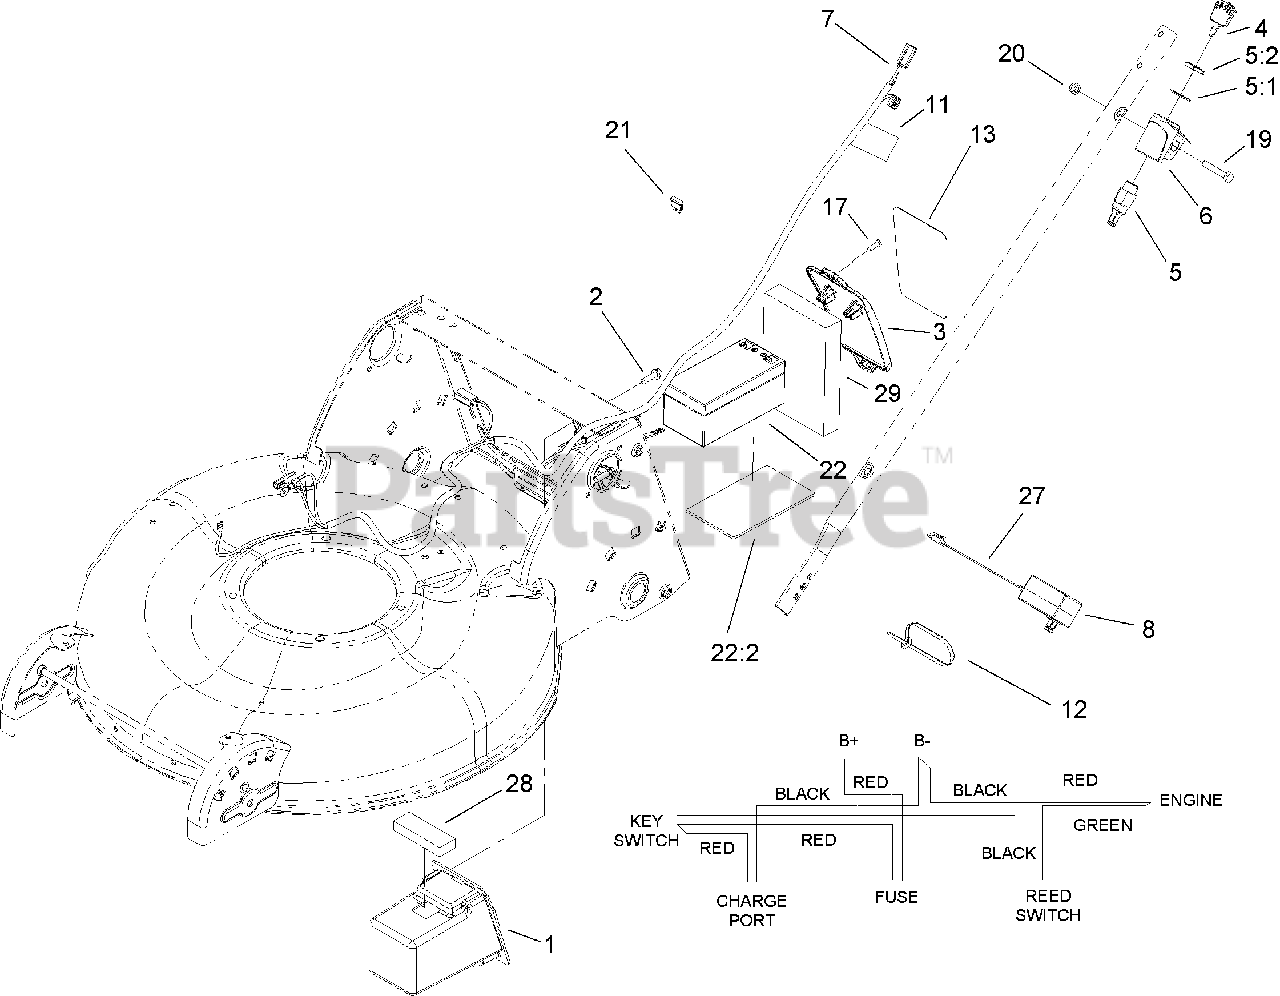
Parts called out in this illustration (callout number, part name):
1	BOX-BATTERY
2	SCREW-HWH
3	COVER-BATTERY
5	SWITCH-STARTER
5:1	WASHER-TOOTH
6	MOUNT-SWITCH
7	HARNESS-WIRE
8	CHARGER-EUROPEAN, 12V DC
11	DECAL-HARNESS
12	STRAP-TIE
13	DECAL-INSTRUCTION, BATTERY
17	SCREW-PPH
19	SCREW-HH
20	NUT-LOCK, NI
21	FUSE-40 AMP
22:2	FOAM-BATTERY
27	ADAPTER-CHARGER
28	FOAM-SIDEPANEL
29	FOAM-SIDEPANEL
